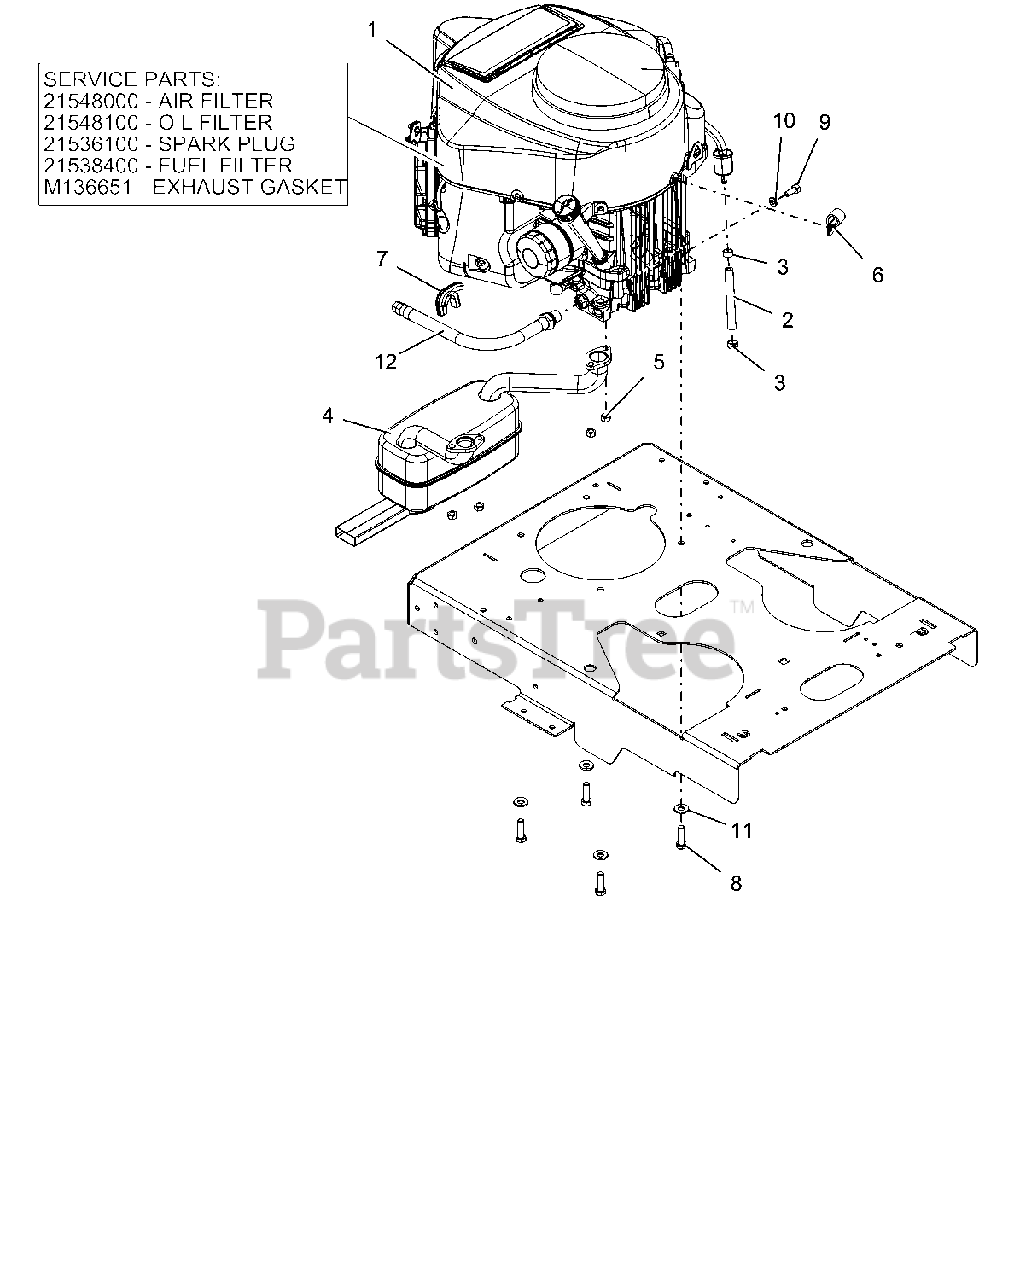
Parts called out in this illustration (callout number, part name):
1	ENGINE, KAWASAKI FR651V
1	AIR FILTER
1	OIL FILTER
1	SPARK PLUG
1	FUEL FILTER
1	EXHAUST GASKET
2	.25 LOW-PERM GAS HOSE 4.00" LG - TANK TO ENGINE
3	CLAMP, FUEL LINE
4	MUFFLER, KAWASAKI
5	NUT-LK-TOP M8-1.25 YWZC
6	CLAMP, CUSHIONED STEEL .75
7	PROTECTOR, OIL DRAIN HOSE
8	BLT-HEX .38-16X1.25 GR5 YWZC NYTORQ
9	@BLT-HEX M8-1.25X20 YWZC
10	WSHR-LK .31X.078 REG YWZC
11	WSHR, 3/8" SPRING DISC
12	HOSE, OIL DRAIN
